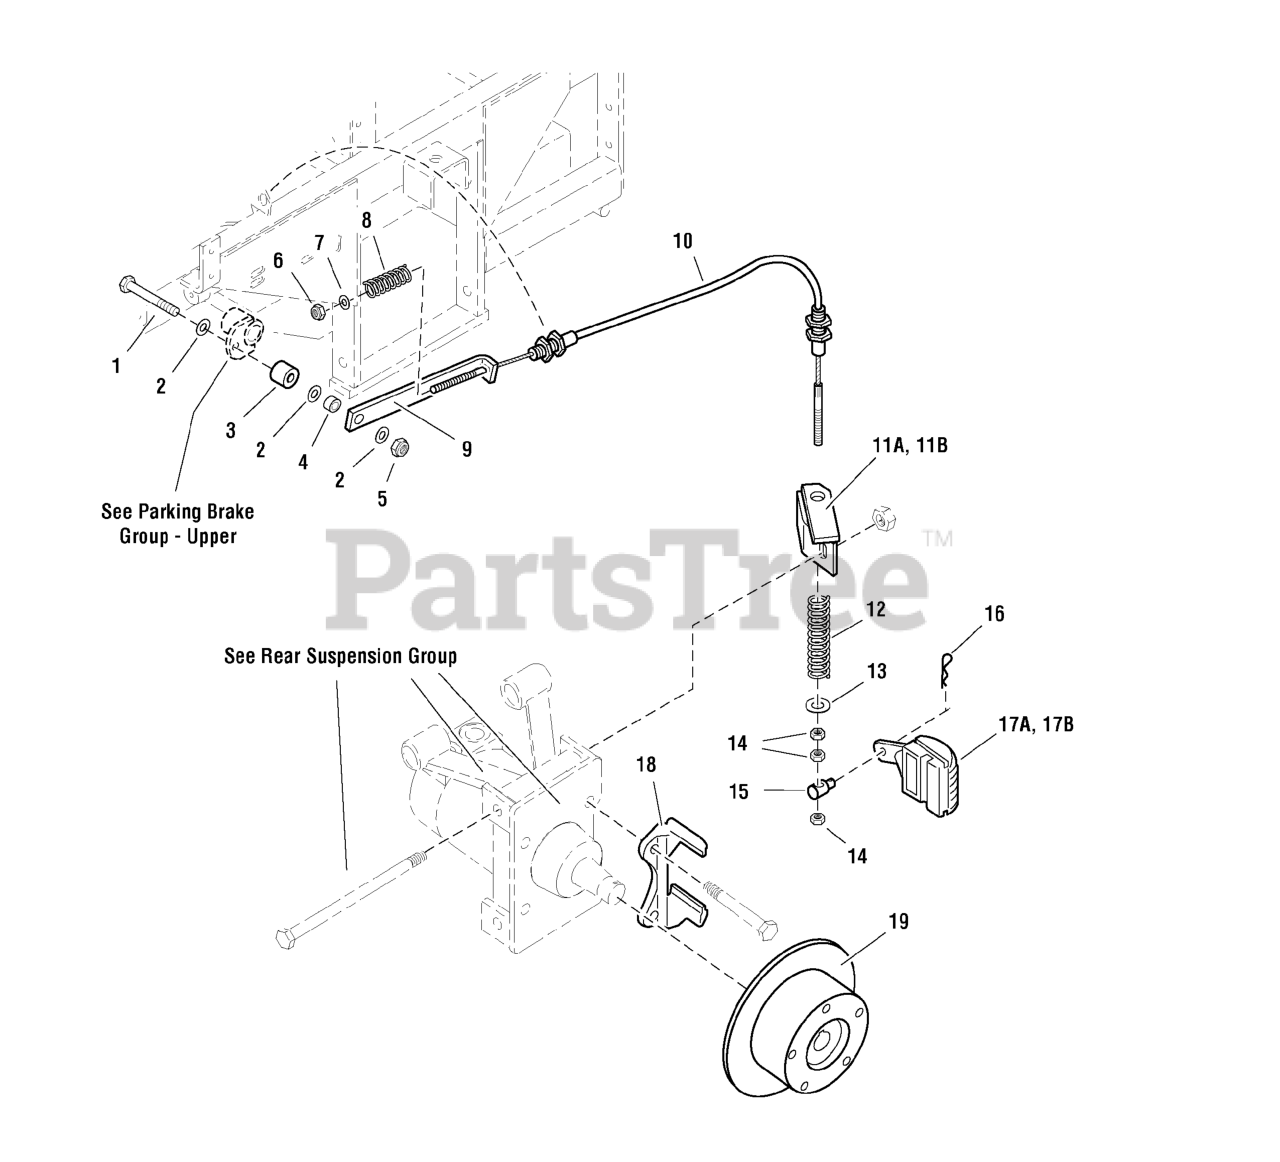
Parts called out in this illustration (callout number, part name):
1	BOLT, 3/8-16 X 2-1/4" GD5 CZ
2	WASHER, 3/8 SAE
3	SPACER, .39 x 1.00 x .88
4	SPACER, .38 x .50 x .27
5	NUT, 3/8-16 HEX NYLON LOCK
6	NUT, 5/16-24 HEX NYLON LOCK
7	WASHER, 5/16" SAE
8	SPRING, Compression
9	LINK, Brake Lock
10	CABLE, Brake
11A	BRACKET, Cable Mount-LH
12	SPRING, Compression
13	WASHER, 5/16" Fender
14	NUT, 5/16-24 Hex
15	ADJUSTER, Brake Linkage
16	HAIRPIN CLIP
17A	BRAKE CALIPER, LH
18	MOUNT, Brake Caliper
19	HUB, 8" Brake Disc
20	KIT, BRAKE PAD REPLACEMENT
